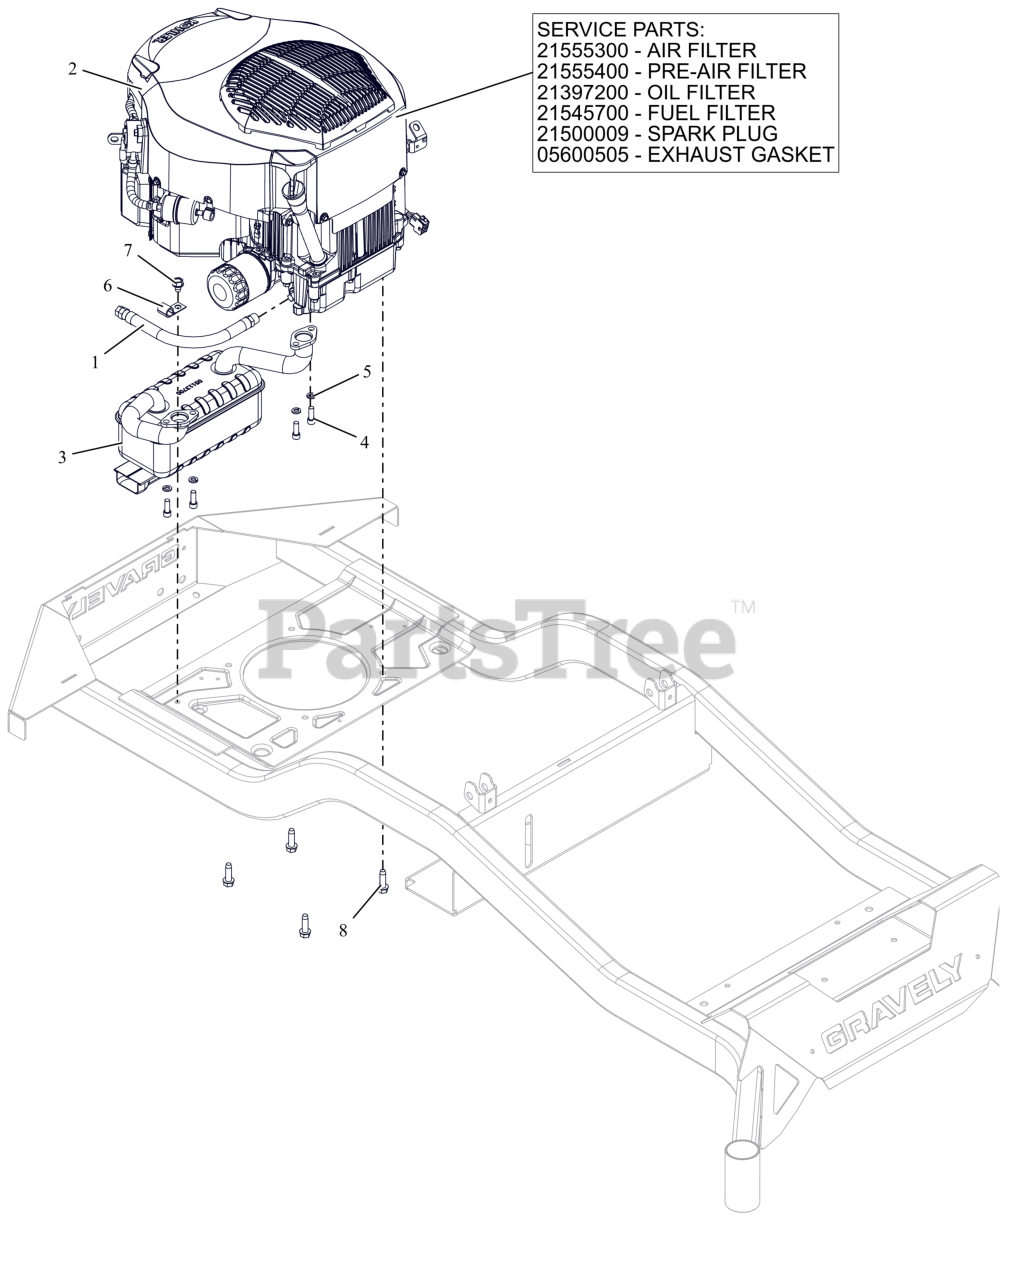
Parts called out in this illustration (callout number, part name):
1	HOSE, OIL DRAIN
2	ENGINE, KOHLER - KT740
2	AIR FILTER, KOHLER
2	PRE CLEANER, KOHLER
2	FILTER, OIL - KOH CV20
2	FILTER-FUEL KOHLER COURAGE PRO
2	PLUG, SPARK KOHLER
2	GASKET, MUFFLER KOHLER TWIN
3	MUFFLER, KOHLER
4	SCR, SKH .312-18X.875 GR8 ZCC
5	WSHR,LK-REG .312X.078 ZCC
7	SCR,TAP .375-16X.50 HWH TR ZCC
8	SCR,TAP .375-16X1.25HWH TR ZCC
